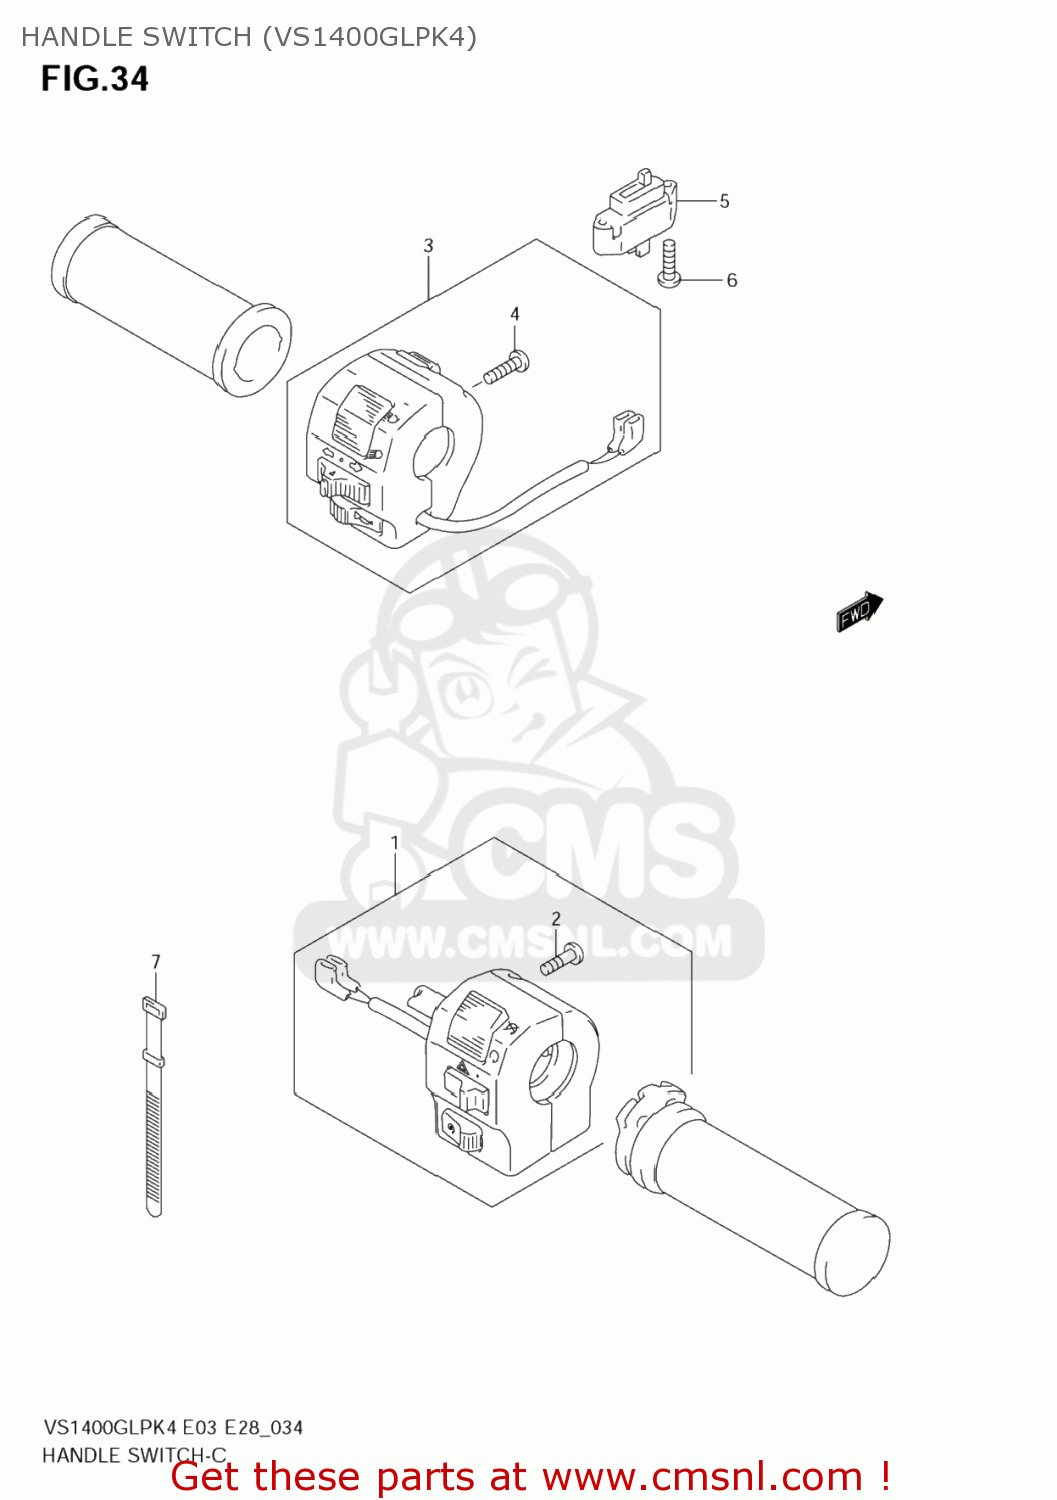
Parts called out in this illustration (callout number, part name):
1	SWITCH ASSY,HANDLE,R
2	SCREW
3	SWITCH ASSY,HANDLE,L
4	SCREW
5	SWITCH ASSY,CLUTCH
6	SCREW
7	CLAMP
